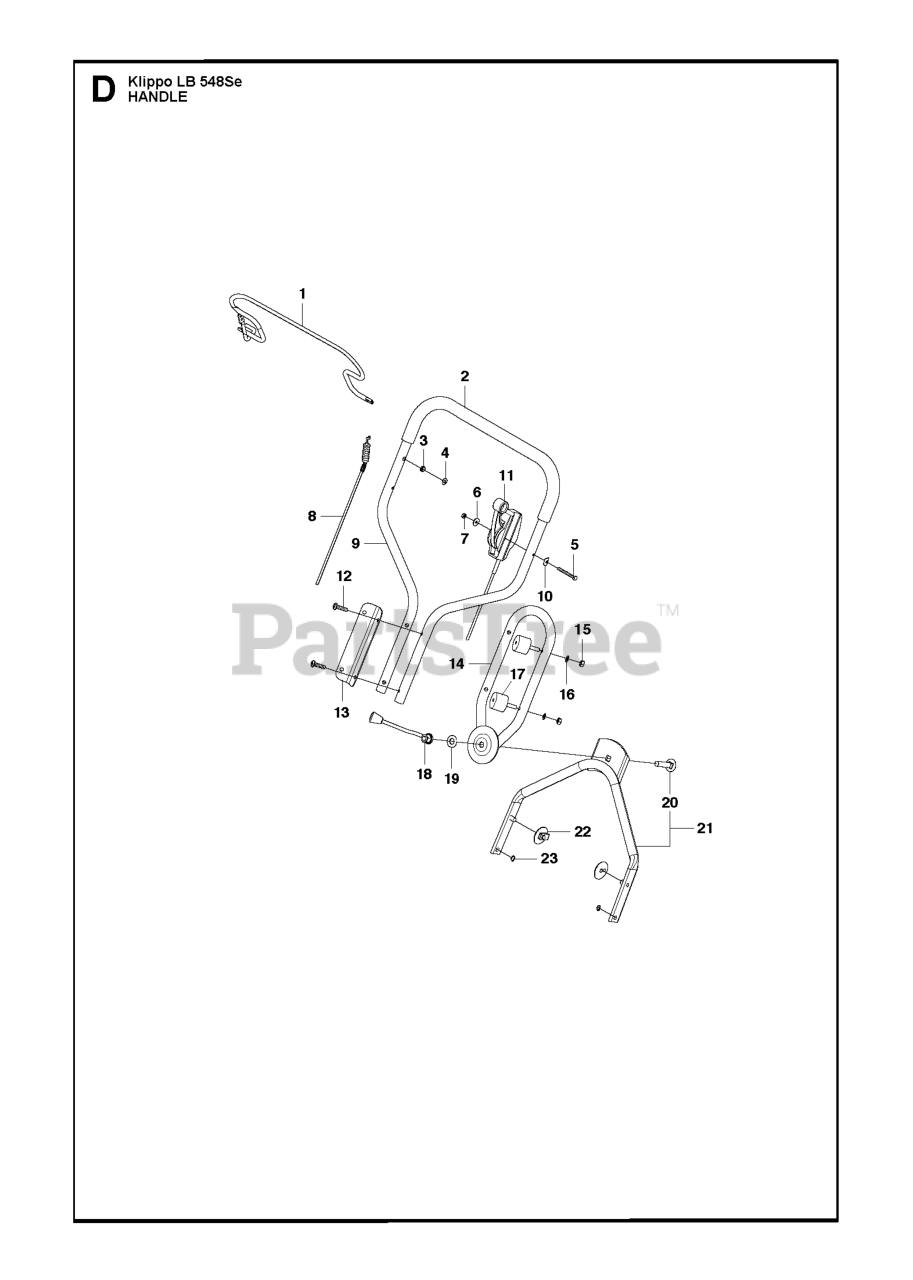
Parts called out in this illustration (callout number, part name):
5	SCREW M6X55
7	NUT FLANGE - M6
15	NUT
23	RETAINING RING SGA 10
